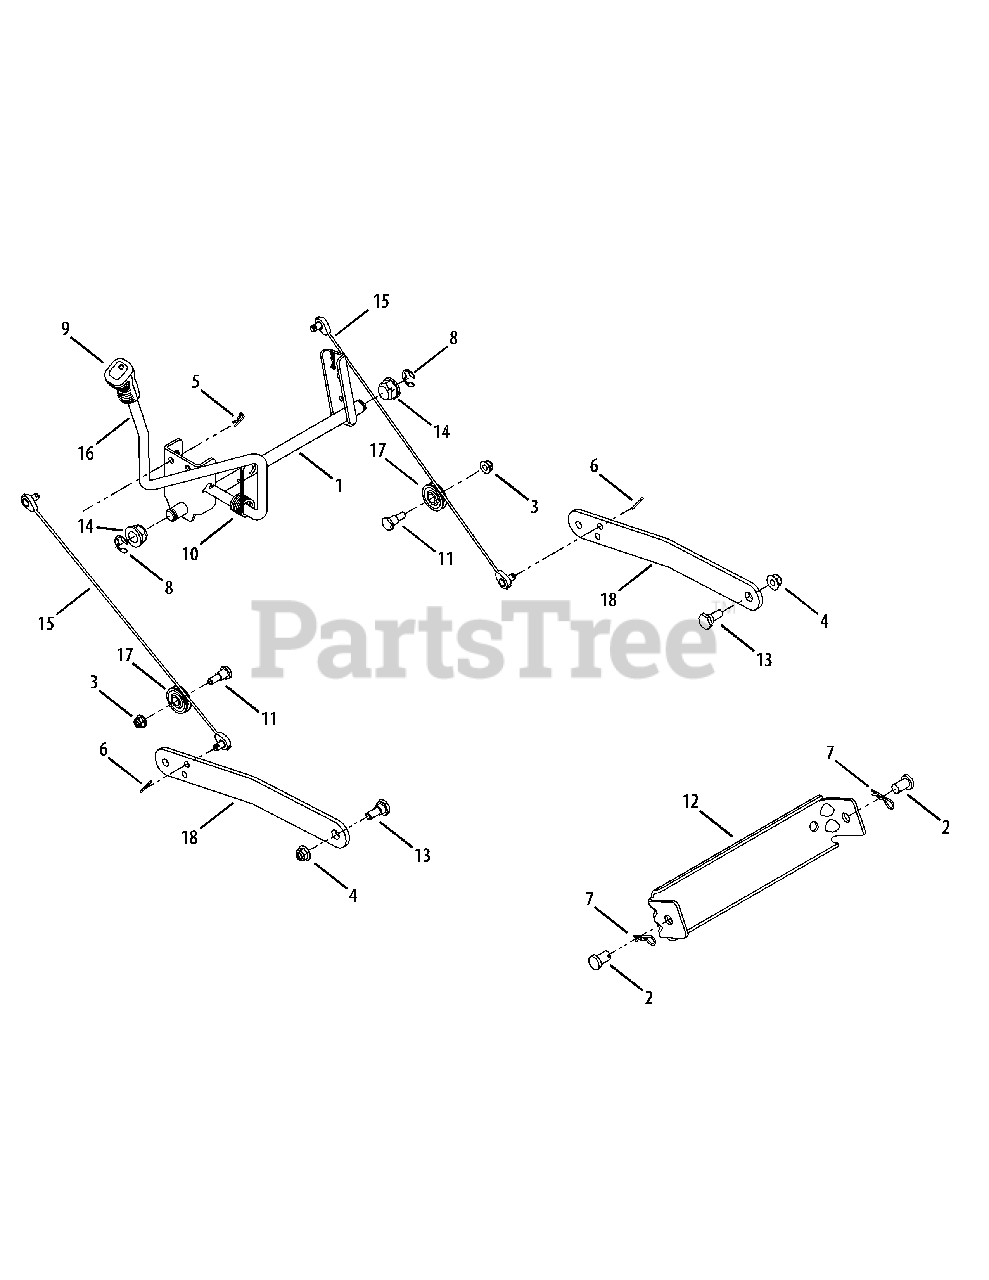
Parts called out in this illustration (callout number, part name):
3	Nut, Nylon Lock, 5/16-18, Gr5
4	Nut, Nylon Lock, 3/8-16
5	Pin, Cotter, .072 Dia. x 1.13 Lg
6	Pin, Cotter, 3/32, 1.0
7	Pin, Click, .092 x 1.64 Lg
8	E-ring, .625 Dia. Shaft
9	Grip, Handle
10	Spring, Torsion
11	Screw, Hex Cap, 5/16-18x.620 Gr2
13	Shldr. Screw, 3/8-16
14	Bearing, Hex Flange
15	Cable, Lift, 16.16 Lg
16	Handle, Lift
17	Pulley, Roller
